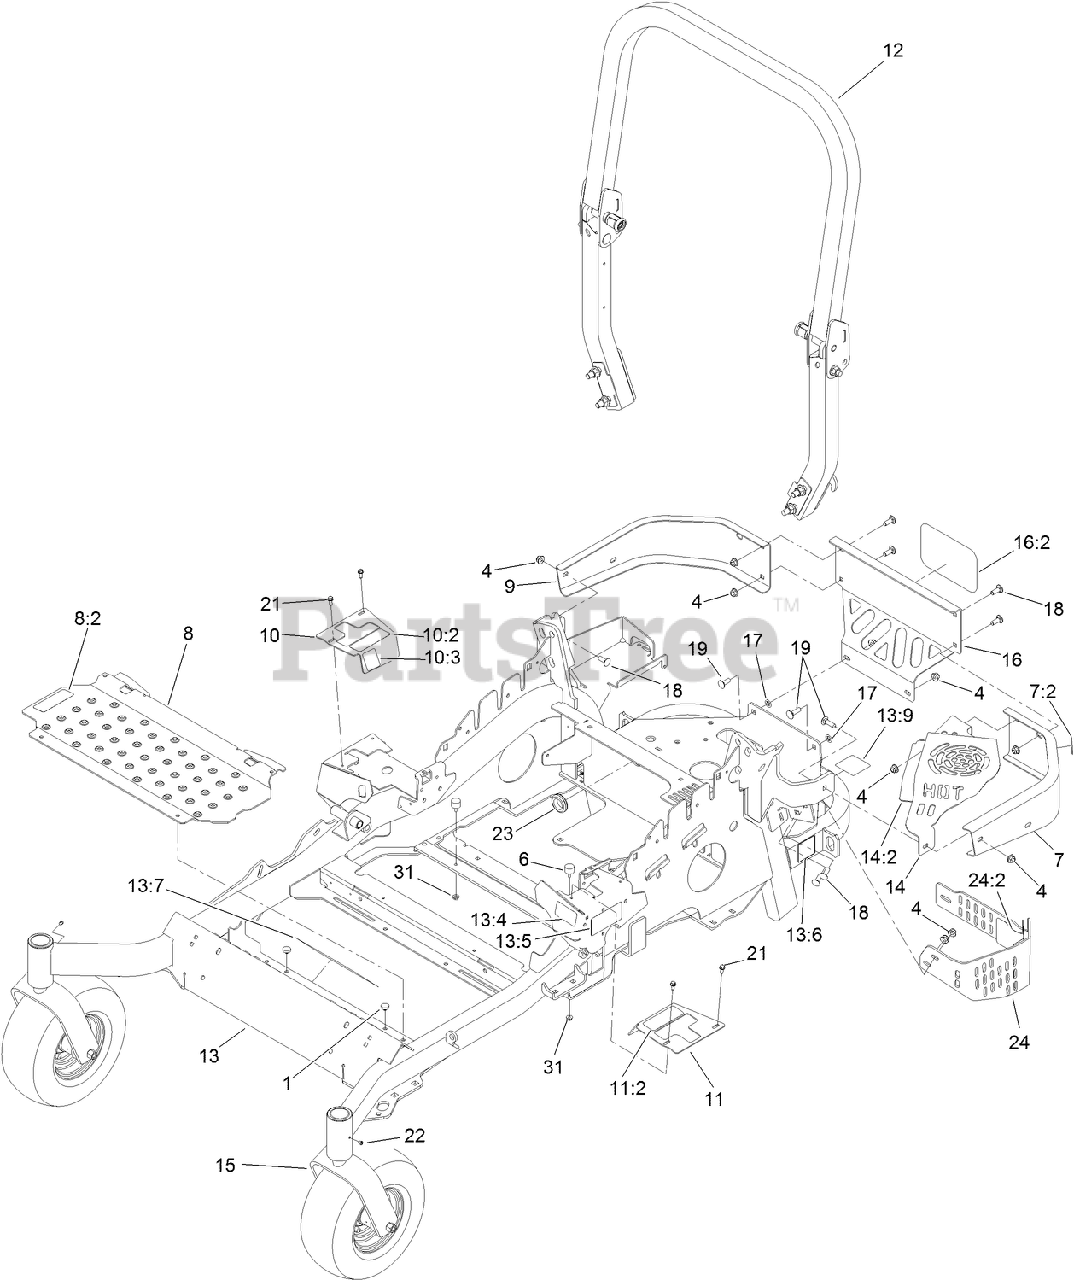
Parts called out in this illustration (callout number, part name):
1	BUMPER
4	NUT-HF, NI
6	BUMPER-RUBBER (W/ STUD)
7	BUMPER-REAR, LH
7:2	DECAL-WARNING
8	FLOORPAN ASM
8:2	DECAL-MISSING, COVER
9	BUMPER-REAR, RH
10	RH MOTION CONTROL COVER ASM
10:2	DECAL-CONTROL, MOTION
10:3	DECAL-PARK BRAKE, CE
11	MOTION CONTROL COVER ASM
11:2	DECAL-CONTROL, MOTION
12	ROPS ASM
13	FRAME ASM
13:4	DECAL-FUEL FILL, CE
13:6	DECAL-HAZARD, PINCHED FINGER
13:7	DECAL-WARNING, SLOPE
13:9	DECAL-BYPASS
14	MUFFLER GUARD ASM W/FOIL
14:2	FOIL-TAPE
15	FRONT CASTER ASM
16	REAR GUARD ASM
16:2	DECAL
17	NUT-PUSH
18	SCREW-CARR
19	BOLT-CARR
21	SCREW-HWH
23	GROMMET
24	LH LOWER MUFFLER GUARD ASM
24:2	DECAL-WARNING
31	NUT-HF
